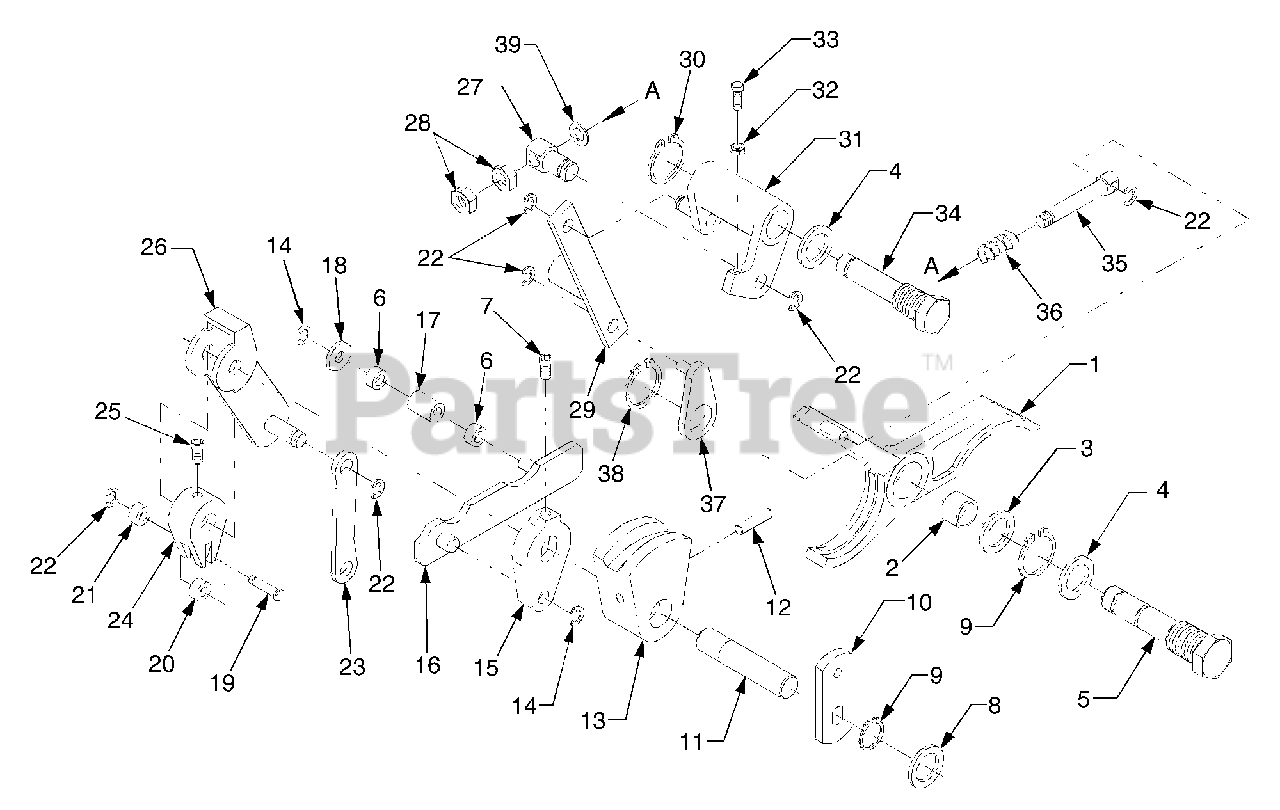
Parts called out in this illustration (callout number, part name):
2	Bearing, Needle
18	Washer, Plain
39	Washer, Plain
